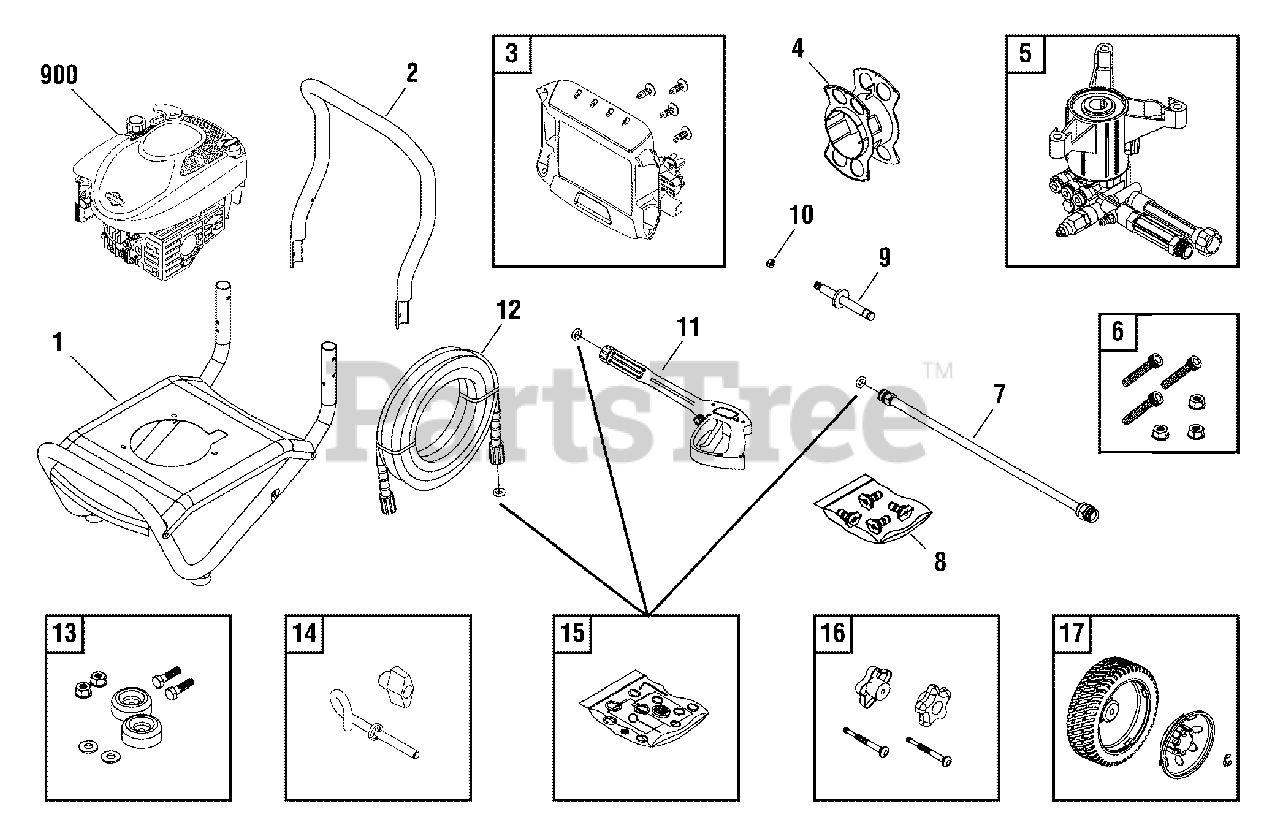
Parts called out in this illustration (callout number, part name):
5	PUMP
6	KIT, Hardware, Pump Mounting
7	EXTENSION, QC
8	KIT, QC Nozzles
10	NUT
11	GUN
12	HOSE
13	MOUNT, Vibration
15	KIT, O-Rings
16	KIT, Hardware, Handle
900	* ENGINE
